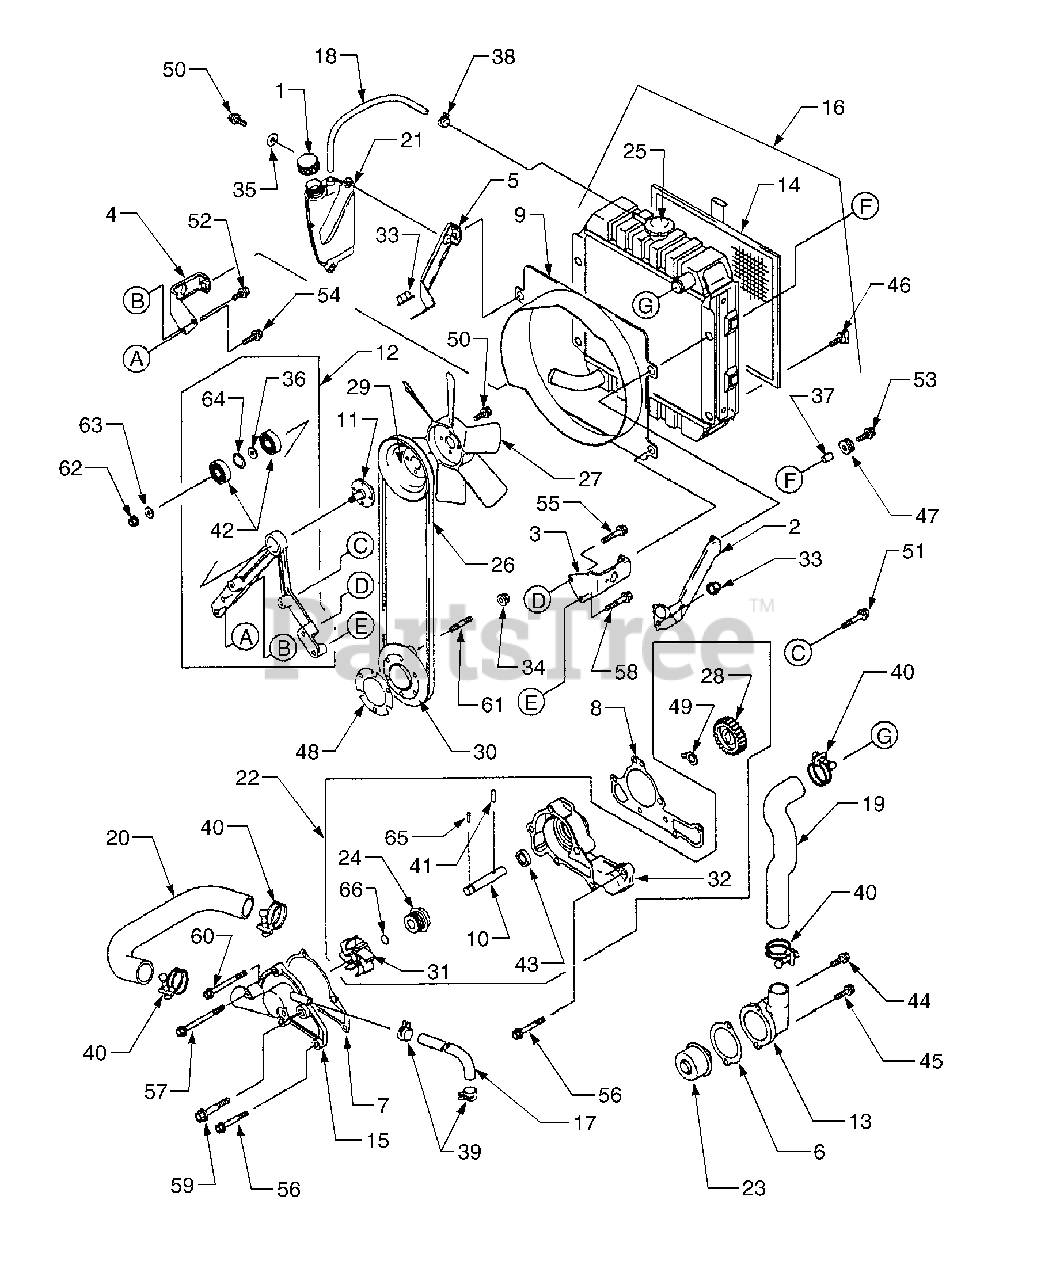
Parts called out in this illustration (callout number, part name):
1	Cap, Reservoir
6	Gasket, Thermostat Cover
7	Gasket, Pump Cover
8	Gasket, Pump Case
10	Shaft, Impeller
11	Shaft, Pulley
12	Housing Assembly
13	Cover, Thermostat
15	Cover, Pump
16	Radiator Assembly
17	Hose, Cooling, 7.5 x 13.5 x 30.5
18	Hose, Cooling, 7.5 x 10.5 x 46
19	Hose, Cooling
20	Hose, Cooling
22	Pump, Water
24	Seal, Mechanical
25	Cap Assembly, Pressure
36	Spacer, 12 x 18 x 1.4
42	Bearing, Ball
44	Bolt, .6 x 40
45	Bolt, .6 x 20
48	Shim, 0.6 Thk
50	Bolt, Flanged, 6 x 16
51	Bolt, Flanged, 6 x 35
52	Bolt, Flanged, 8 x 20
53	Bolt, Flanged, 8 x 25
54	Bolt, Flanged, 8 x 30
55	Bolt, Flanged, 8 x 40
56	Bolt, Flanged, 6 x 45
57	Bolt, Flanged, 6 x 75
58	Bolt, Flanged, 8 x 45
59	Bolt, Flanged, 8 x 70
60	Bolt, Flanged, 6 x 65
62	Nut, Hex Fine
63	Washer, Plain
